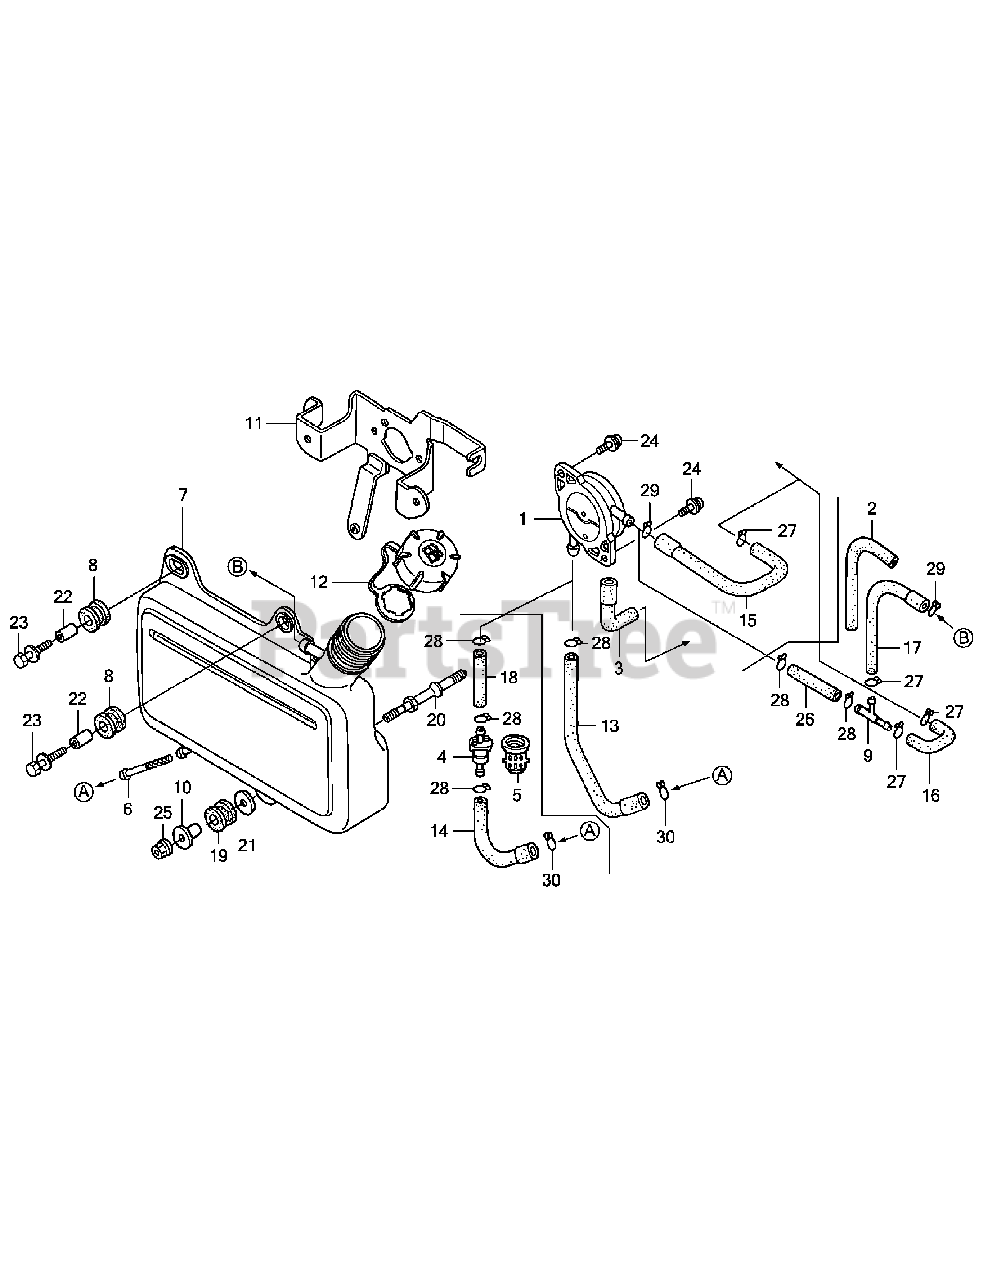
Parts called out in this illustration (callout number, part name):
1	Pump Assembly, Fuel
2	Rubber Supporter (107mm)
3	Tube, Diaphragm
4	Strainer Complete, Fuel
5	Suspension, Strainer
7	Tank, Fuel
8	Rubber B, Tank Mounting
9	Joint, Fuel Tube
10	Collar, Front Cover Setting
11	Stay A, Fuel Tank
12	Cap Assembly, Fuel Tank
14	Tube, Fuel Tank
16	Tube, Fuel
17	Tube, Fuel Return
18	Tube, Fuel Pump
19	Cushion, RR Fender
20	Bolt, Fuel Tank Stud
21	Washer, 6mm
22	Collar, 14 x 6.1
23	Bolt, Washer 6 x 25
24	Screw, Washer 5 x 14
25	Nut, Flange 6mm
26	Tube, Fuel 5.3 x 33
27	Clip, Tube (B8)
28	Clip, Tube (B10)
29	Clip, Tube (C9)
30	Clip, Tube (C11)
